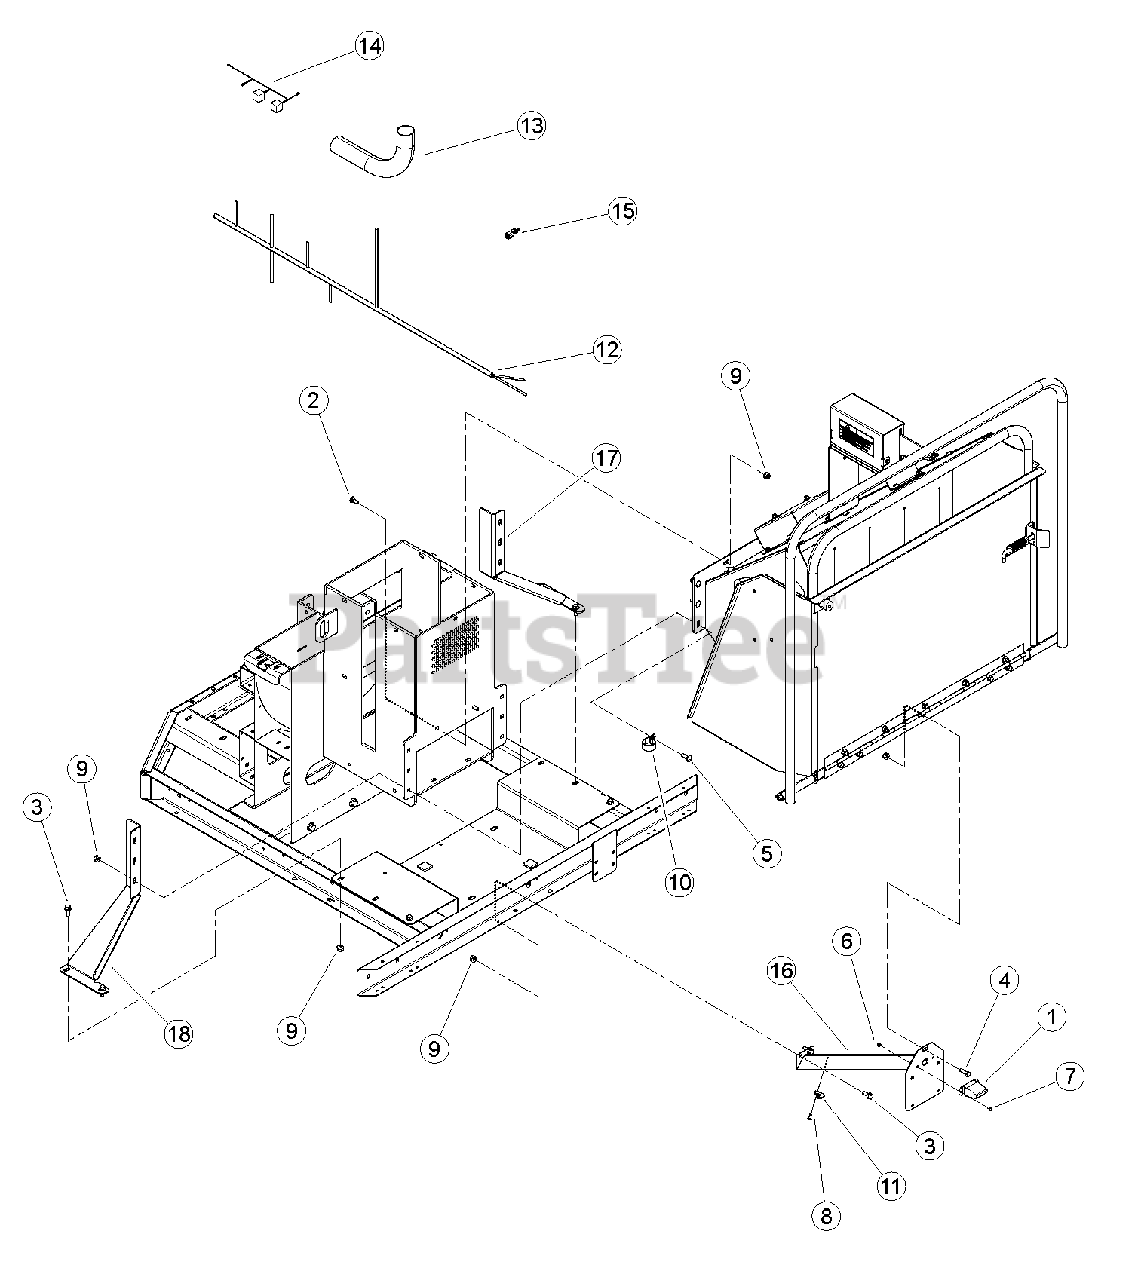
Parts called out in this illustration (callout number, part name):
1	LIGHT, LICENSE PLATE
2	BOLT, 3/8 X 1" GR5 CRG NC ZP
3	BOLT, 3/8 X 1 FLANGE NC
4	BOLT, 3/8 X 1-1/4" HEX HD GR5 ZP
5	BOLT, 3/8 X 1-1/4" GR5 CRG NC ZP
6	NUT, 10/24 NYLOCK TYPE NM ZP
7	SCREW, MCH 10-24 X 1/2" PAN HD PH ZP
8	RIVET, AL BLIND 1/4 X 3/4 DOME HEAD
9	NUT, 3/8-16 NYLOCK FLANGE
10	CLAMP, 1 9/16 COATED METAL
11	CLAMP, CABLE MOUNT
12	HARNESS, 6 IN GAS PLUS 1 CONTROLLER
13	SLEEVING, BRAIDED ELECTRICAL HARNESS
14	HARNESS, CARB SAFETY RELAY
15	PLUG, JUMPER HARNESS
16	WELDMENT, CHUTE SUPPORT
17	PLATE, CHIPPER SUPPORT RH
18	PLATE, CHIPPER SUPPORT LH
